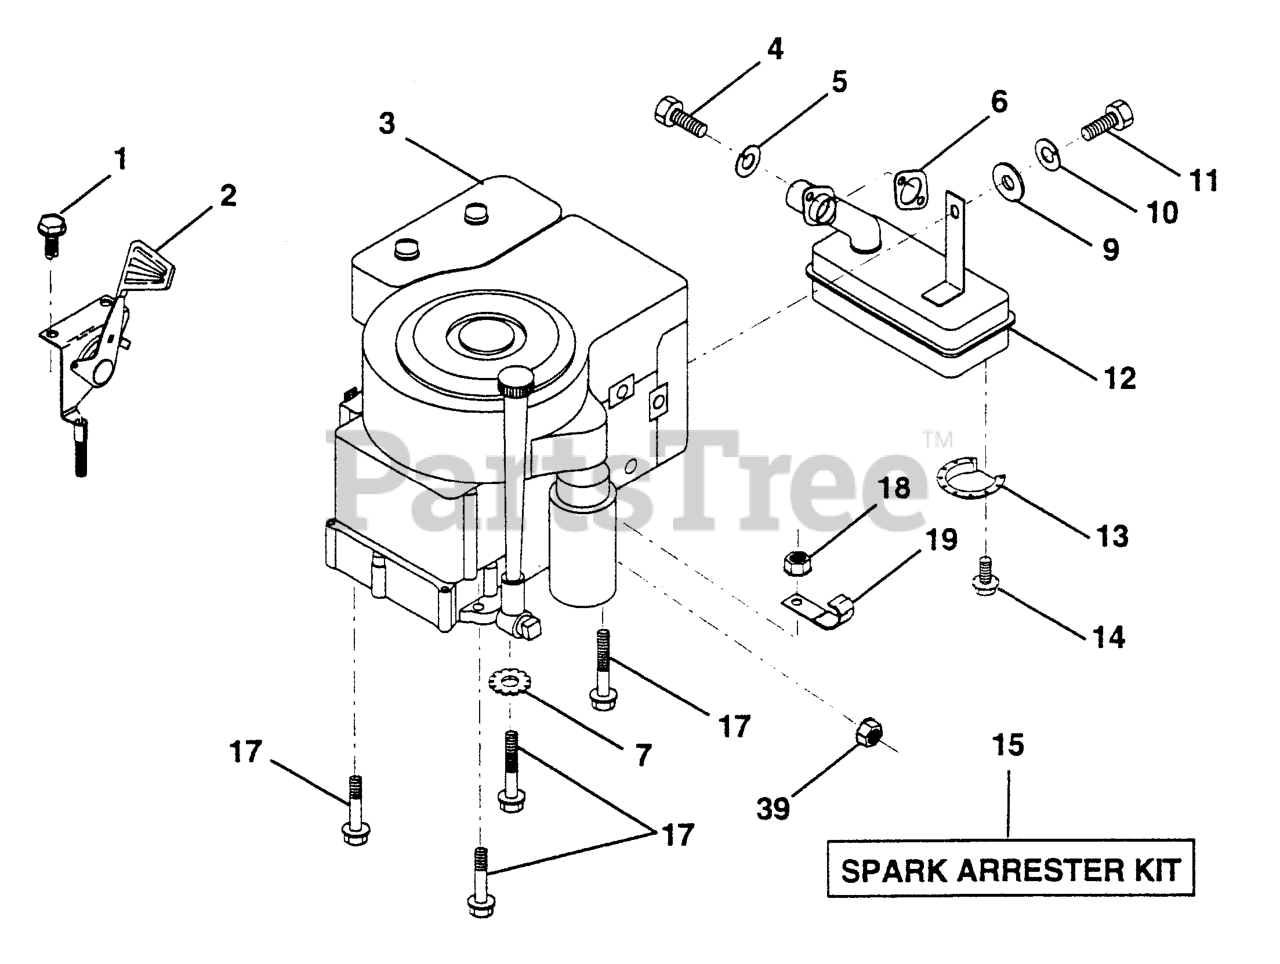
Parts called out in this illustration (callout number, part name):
2	CONTROL.TH/CH.RH.BLK.FLG.EEC
3	Engine, B&S, 13 HP, Vanguard Dual Model Number 28P777
5	WASHER.LOCK.HVY.HLCL.SPR.5/16
6	GASKET ENGINE
7	LOCKWASHER
10	LOCKWASHER
11	SCREW
12	MUFFLER NLA
13	DEFLECTOR, MUFFLER
14	SCREW
15	KIT.SPARK ARRESTOR 794945 B&S
16	STOP THROTTLE
17	SCREW LT
18	NUT
19	CLIP T
24	SCREW
25	Screw Hex SKT 5/16 UNC x 3/4
26	WASHER LT
39	NUT
